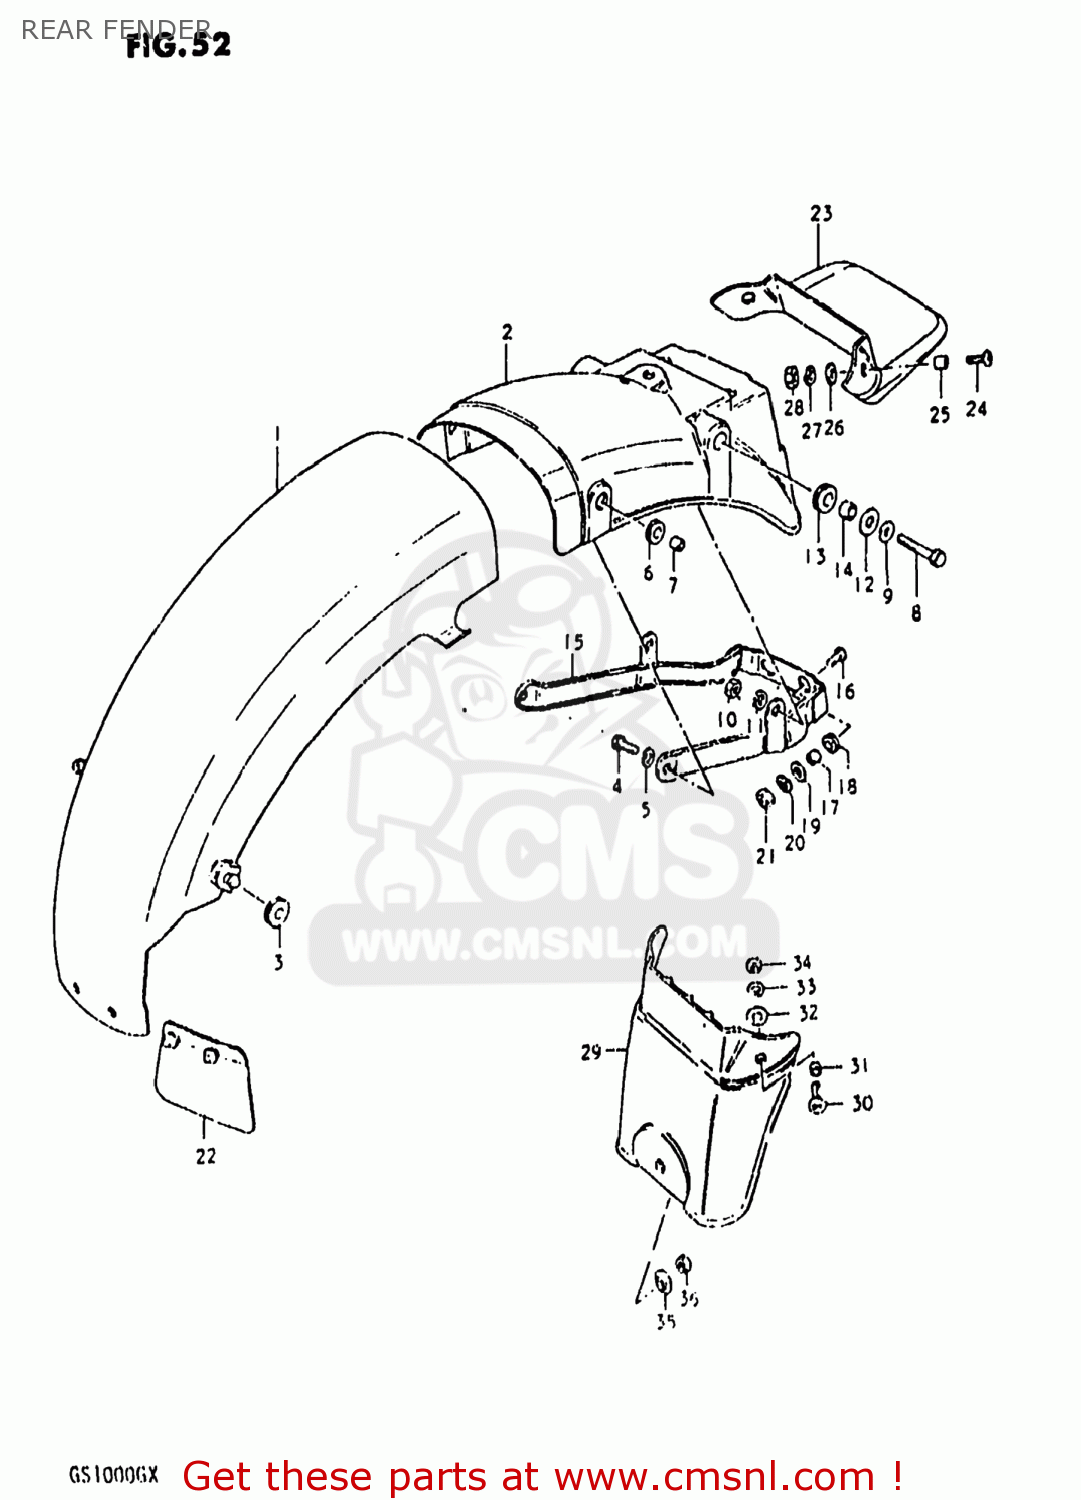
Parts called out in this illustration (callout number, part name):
1	FENDER,REAR
2	BODY,RR FENDER RR
3	CUSHION
4	BOLT
5	LOCK WASHER
6	CUSHION
7	SPACER(6.1X9X7.5)
8	BOLT
9	WASHER
10	NUT
11	LOCK WASHER
12	WASHER(8.5X26X1.2)
13	CUSHION
14	SPACER (8.2X12X7.5)
15	REINFORCEMENT,REAR FENDER
16	SCREW
17	SPACER (6.1X9X9)
18	CUSHION
19	WASHER(6,5X22X1.6)
20	LOCK WASHER
21	NUT
22	GUIDE,RR FENDER MUD
23	EXTENSION,REAR FENDER
24	SCREW (6X15)
25	SPACER(6.2X8.3X5.7)
26	WASHER(6.5X18X1)
27	LOCK WASHER
28	NUT
29	EXTENSION,REAR FENDER
30	SCREW (6X15)
31	SPACER(6.2X8.3X5.7)
32	WASHER(6.5X18X1)
33	LOCK WASHER
34	NUT
